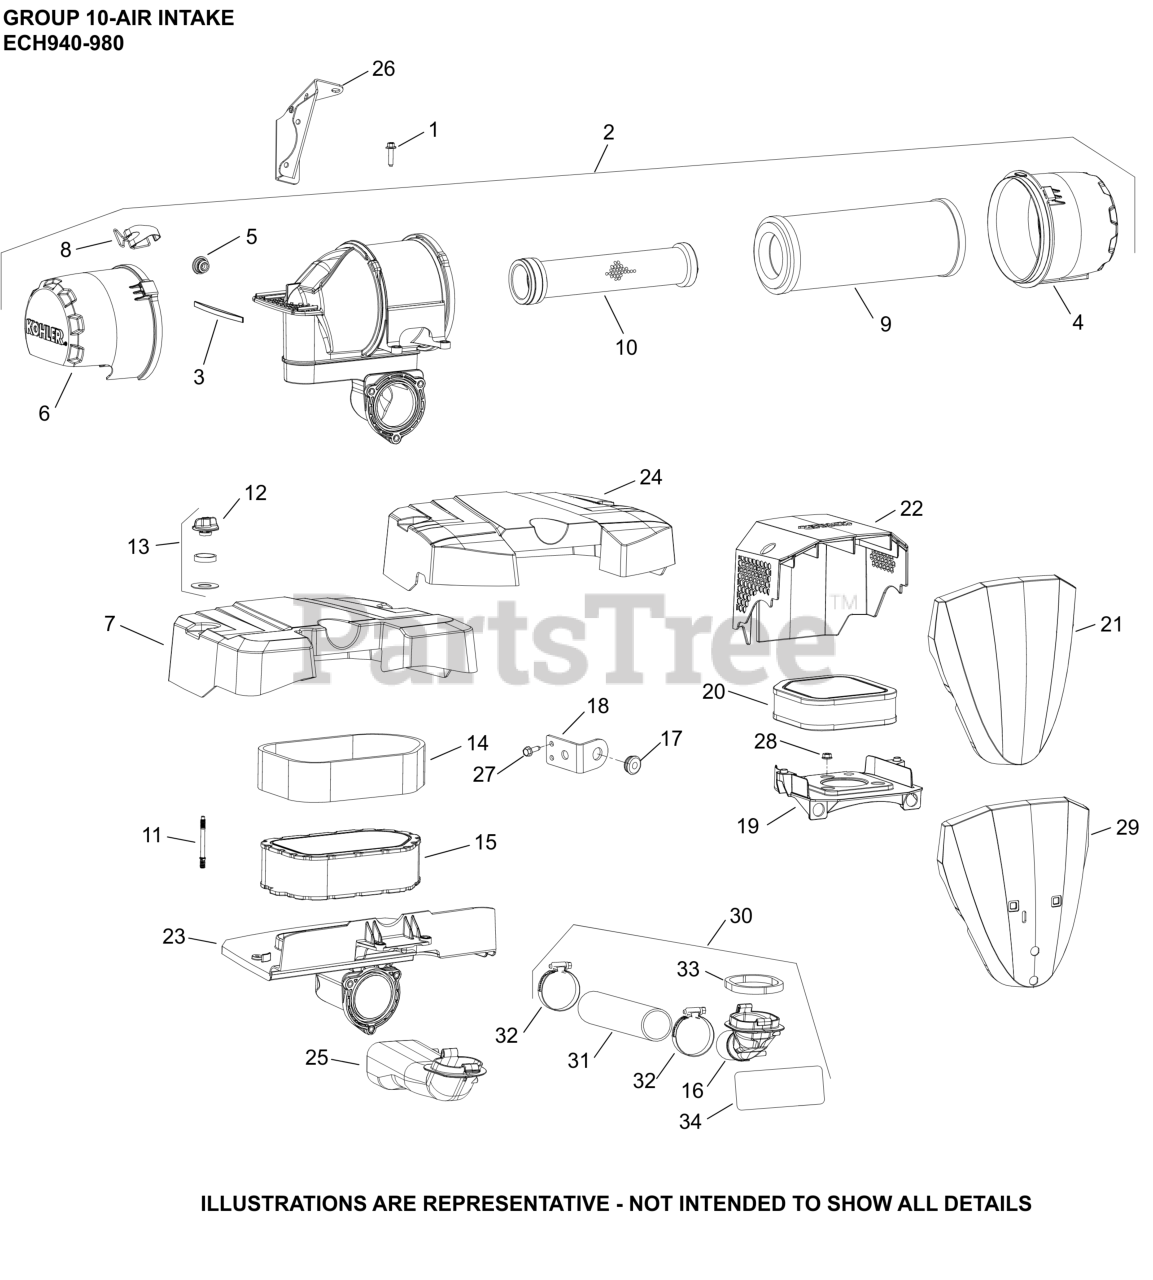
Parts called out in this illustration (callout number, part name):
1	SCREW, FLG M6X1.0X25
2	FILTER ASSEMBLY, AIR
3	DAMPER, FOAM INSERT
4	COVER, AIR FILTER
5	PLUG, HOLE
6	COVER, RAIN CAP
8	CLIP ASSEMBLY
9	ELEMENT, AIR FILTER - PRIMARY
10	ELEMENT, AIR FILTER - SAFETY
14	ELEMENT, PRE-CLEANER
15	ELEMENT, AIR FILTER (LPAC)
23	BASE, AIR CLEANER
